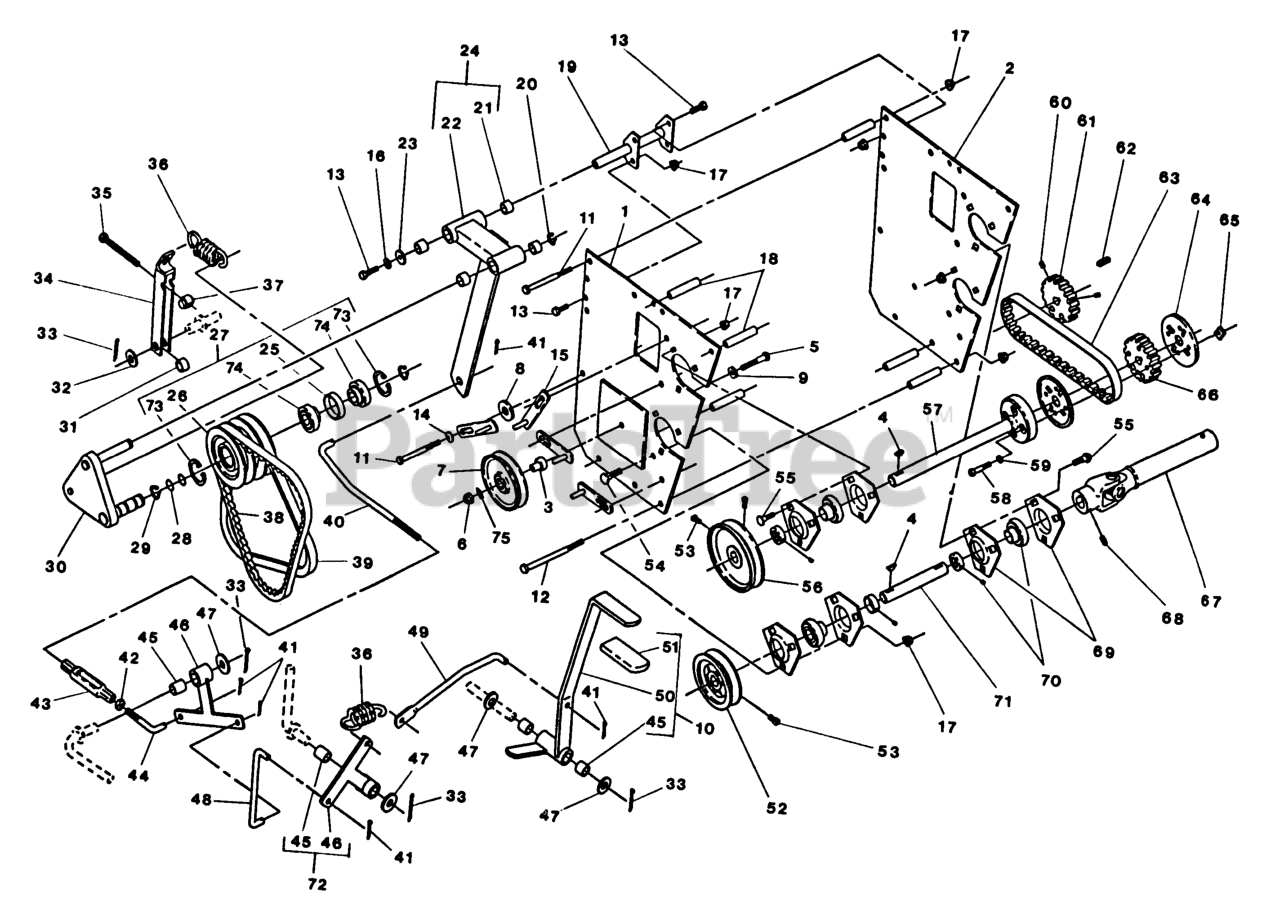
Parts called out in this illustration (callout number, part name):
4	KEY-WOODRUFF
12	SCREW-HH
14	WASHER-SPRING
16	WASHER-LOCK
22	Control Wldm't - Tmfr. Sheave
24	CNTRL ASSY,TRANS SHV
25	SPACER,TRANSFER BEARING
28	O-RING,
36	SPRING,BELT TENSION
37	SWIVEL,BELT TENSION
38	BELT,B SIZE 43.5
39	BELT,SECONDARY DRIVE
40	ROD,PTO LOW RH THD
44	ROD,PTO RH LOW LH THD
45	SLEEVE-BEARING
49	ROD,PTO UPPER
51	GRIP-LEVER
52	SHEAVE,5.5 B
56	SHEAVE,7 B
59	WASHER-LOCK
63	BELT,DRIVE POSITIVE
69	HOUSING-FLANGE
70	BEARING,W/COLLAR
71	JACKSHAFT,PTO
74	BEARING
